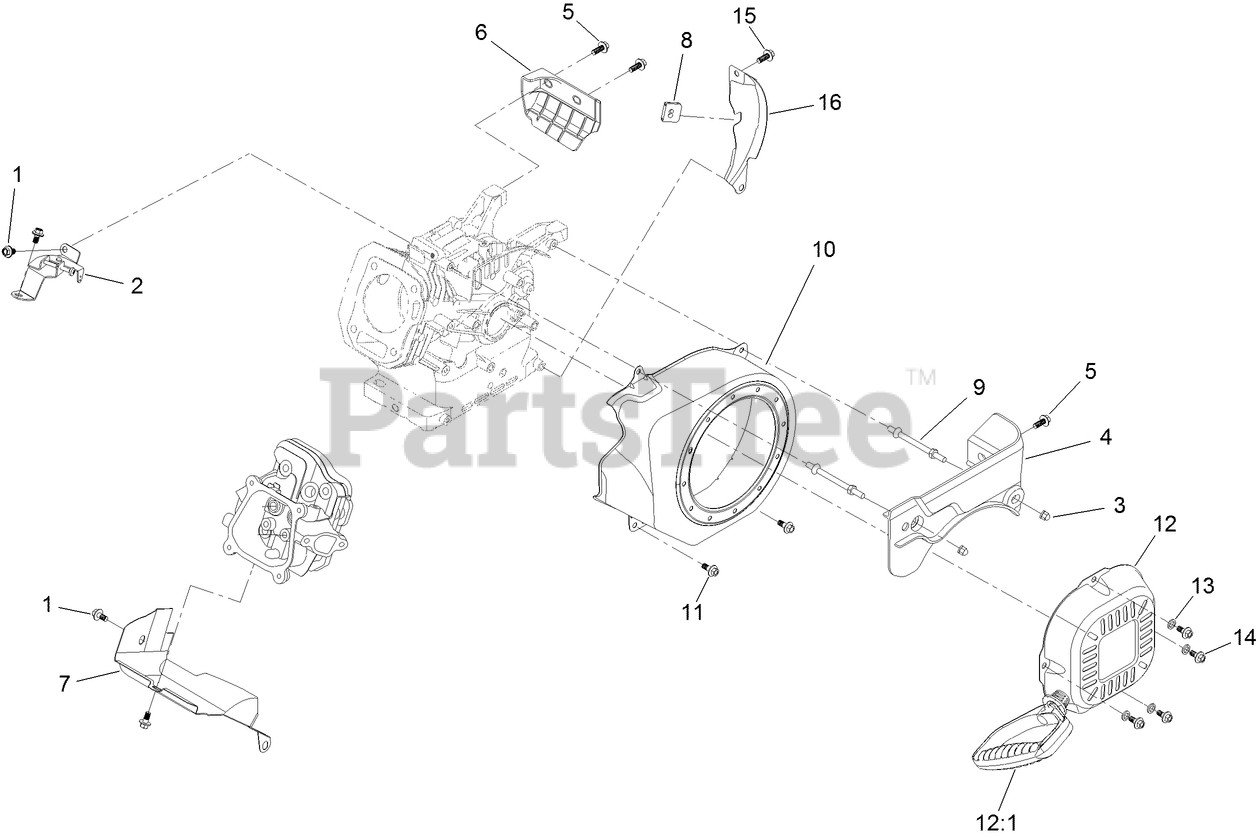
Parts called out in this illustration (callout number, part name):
1	SCREW-HHF
2	SPEED CONTROL ASM
3	NUT-ACORN
4	PANEL-FRONT
5	SCREW-HHF
6	PANEL-SIDE, ENGINE
7	SHROUD-LOWER
8	GROMMET-RUBBER
9	STUD-MOUNT
10	SHROUD-BLOWER
11	SCREW-HHF
12	RECOIL STARTER ASM
12:1	HANDLE-RECOIL
13	WASHER-PLAIN
14	SCREW-HHF
15	SCREW-HHF
16	SHIELD-FLYWHEEL
